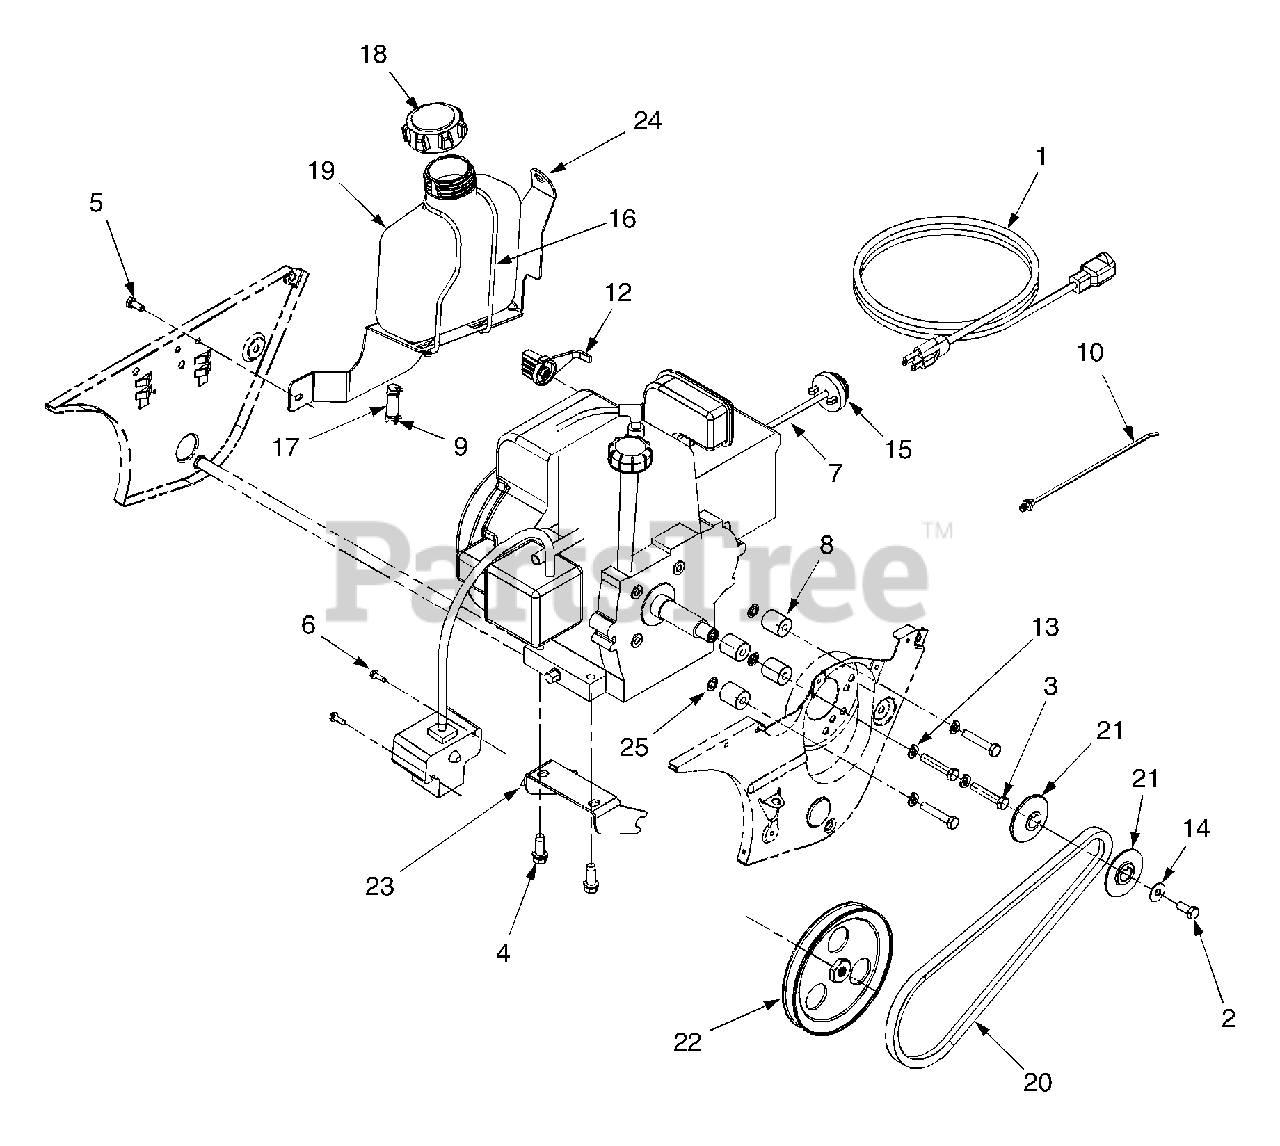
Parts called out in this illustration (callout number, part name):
1	Extension Cord
2	Hex Screw, 5/16-24 x .75
3	Hex Screw, 5/16-24 x 1.75
4	Self Tapping Screw, 3/8-16 x 1.00
5	Hex Screw, 1/4-20 x .62
6	Screw, #10-16 x .625
7	Primer Hose
8	Spacer, Engine
9	Clamp, Hose
10	Cable Tie
12	Knob, Choke
13	Washer, Lock 5/16
14	Bell Washer, .349 x .879 x .063
15	Primer
16	Support, Wire Gas Tank
17	Hose, Fuel Line
18	Cap, Fuel
19	Tank, Fuel
20	V-Belt, 1/2
21	Pulley Half, .625 ID x 2.25 OD
22	Pulley, 1/2 V 1/2-20 LH x 6.0
